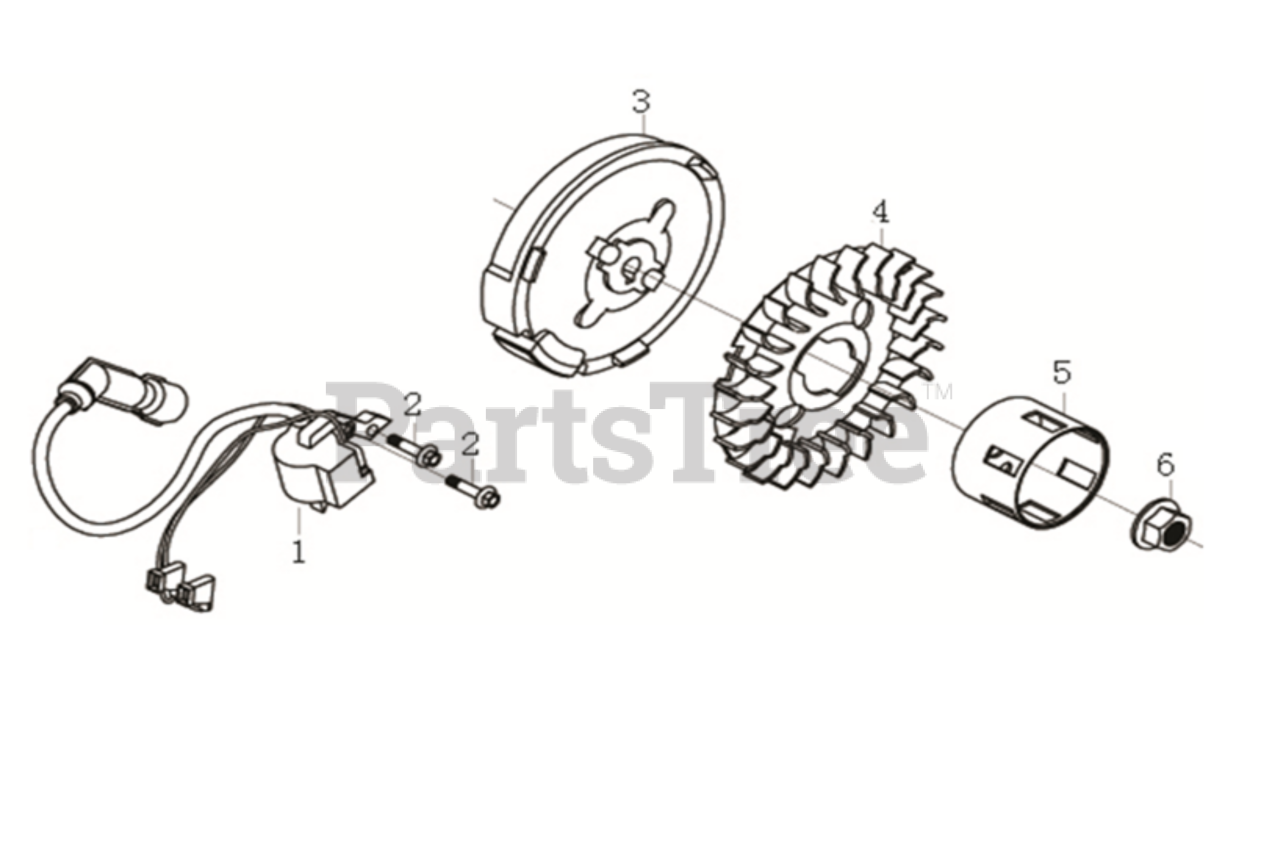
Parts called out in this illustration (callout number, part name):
1	COIL ASSY.,IGNNTION
2	Hexagon bolt with flange
3	FLYWHEEL COMP
4	Impeller
5	Starting disc
6	NUT FLANGE M12
